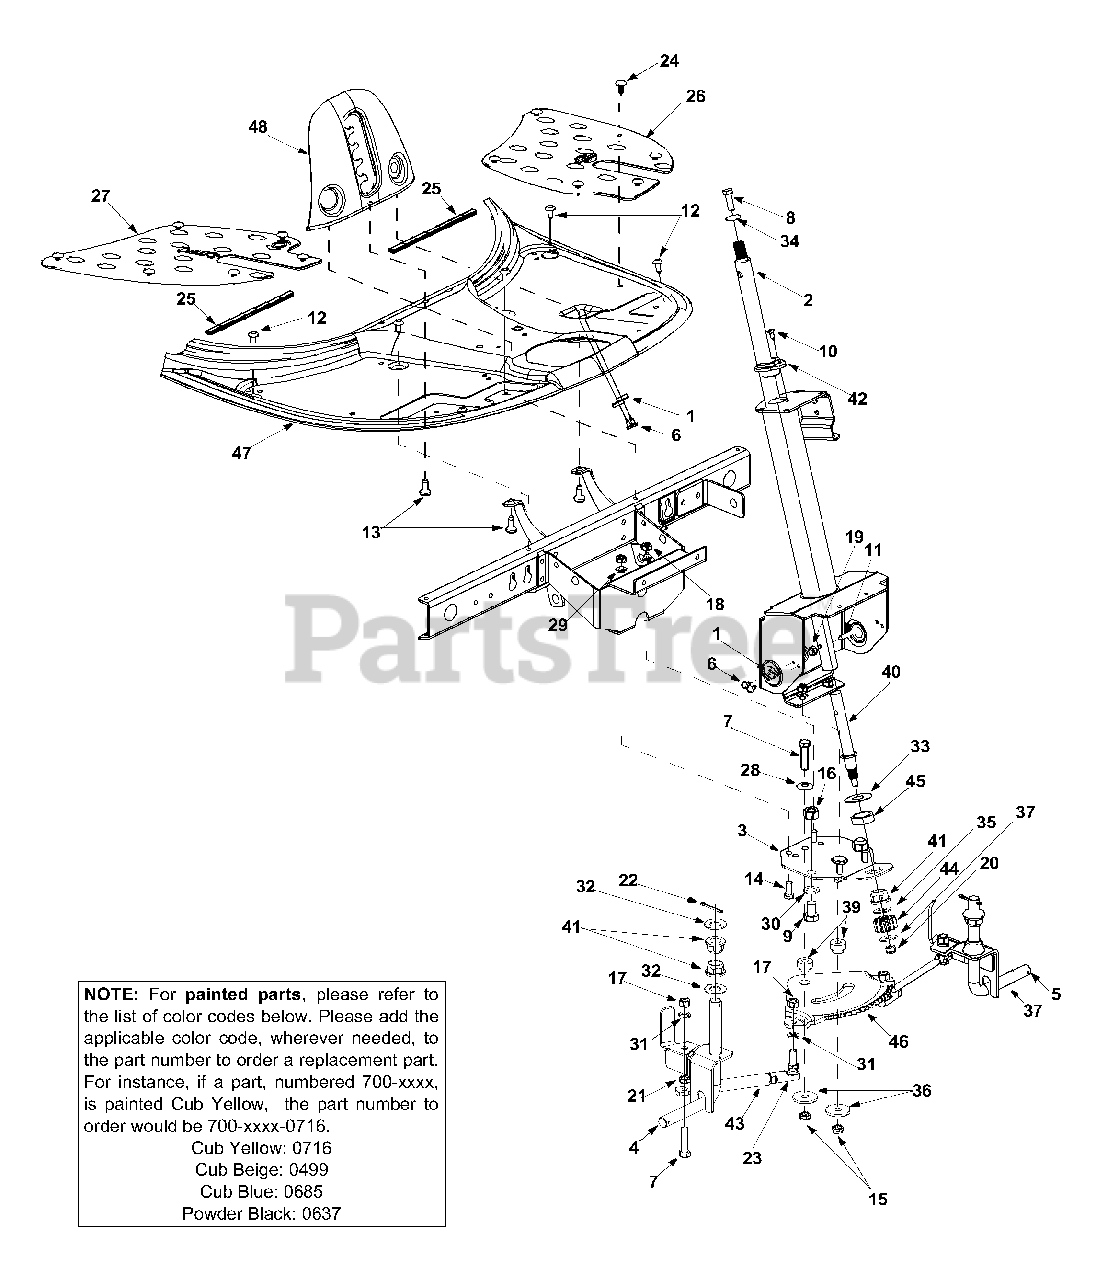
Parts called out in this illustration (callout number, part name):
1	Switch Plate
2	Steering Tube Assembly
3	Steering Support Bracket
4	Front Axle Assembly: RH
5	Front Axle Assembly: LH
6	Hex Screw AB
7	Hex Screw 3/8-24 x 1.5" Gr.5 Sp.
8	Lock Screw 5/16-18 x 1.0" Gr.5
9	Hex Screw 1/2-13 x 0.75"
10	Oval C-Sunk Screw #10-16 x 0.625"
11	Hex Screw 1/4-20 x 1.25 Gr.5 Sp.
12	AB Screw 1/4-14 x 0.625"
13	Self-Tapping Screw 5/16-18 x 0.75"
14	Hex Screw 5/16-18 x 0.75"
15	Lock Nut 3/8-24
16	Hex Nut 1/2-13
18	Hex Nut
19	Lock Nut 1/4-20
22	Cotter Pin
23	Ball Joint
24	Ratchet Clip
25	Trim Strip
26	Floor Pad: LH
27	Floor Pad: RH
28	Bell Washer
29	Lock Washer
30	Flat Washer
31	Lock Washer
32	Flat Washer
33	Flat Washer
34	Beleville Washer
35	Flat Washer
36	Flat Washer
37	Flat Washer
40	Steering Adapter
41	Hex Flange Bearing
42	Bearing: Steering Column
44	Pinion Gear
45	Spacer
46	Gear: Steering Segment
